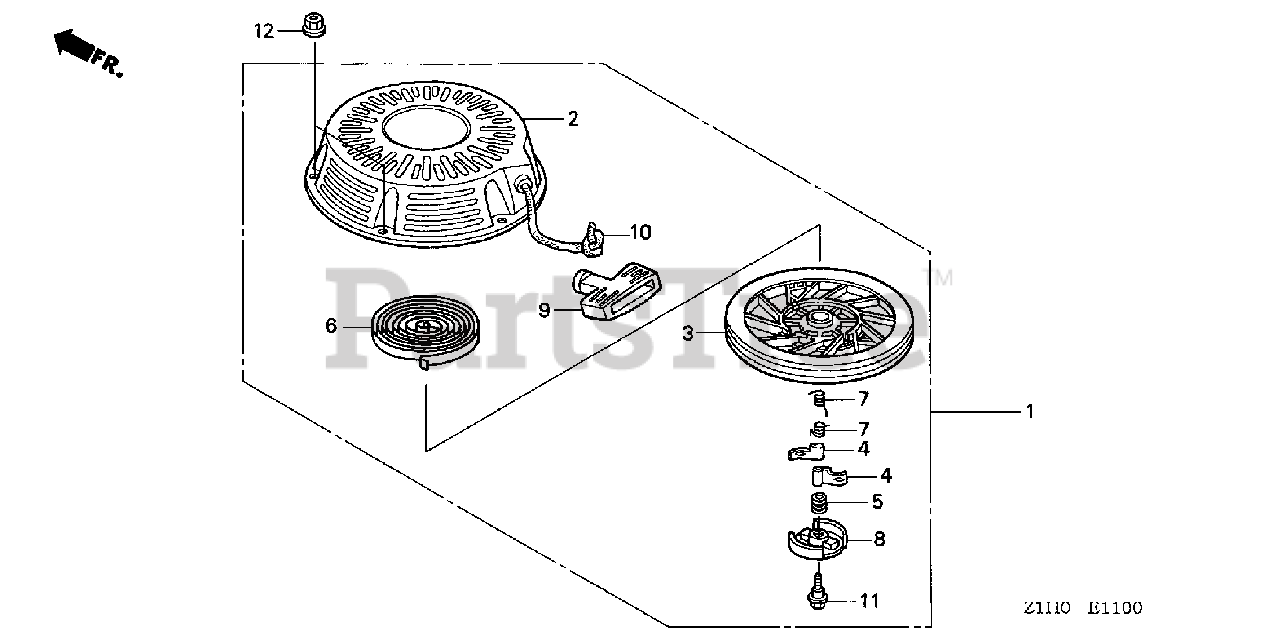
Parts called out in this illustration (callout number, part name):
1	STARTER ASSY., RECOIL *R280* (POWER RED)
2	CASE, RECOIL STARTER *R280* (POWER RED)
3	PULLEY, RECOIL STARTER
4	RATCHET, STARTER
5	SPRING, FRICTION
6	SPRING, STARTER RETURN
7	SPRING, RATCHET
8	RETAINER, SPRING
9	GRIP, STARTER
10	ROPE, RECOIL STARTER
11	SCREW, CENTER
12	NUT, FLANGE (6MM)
